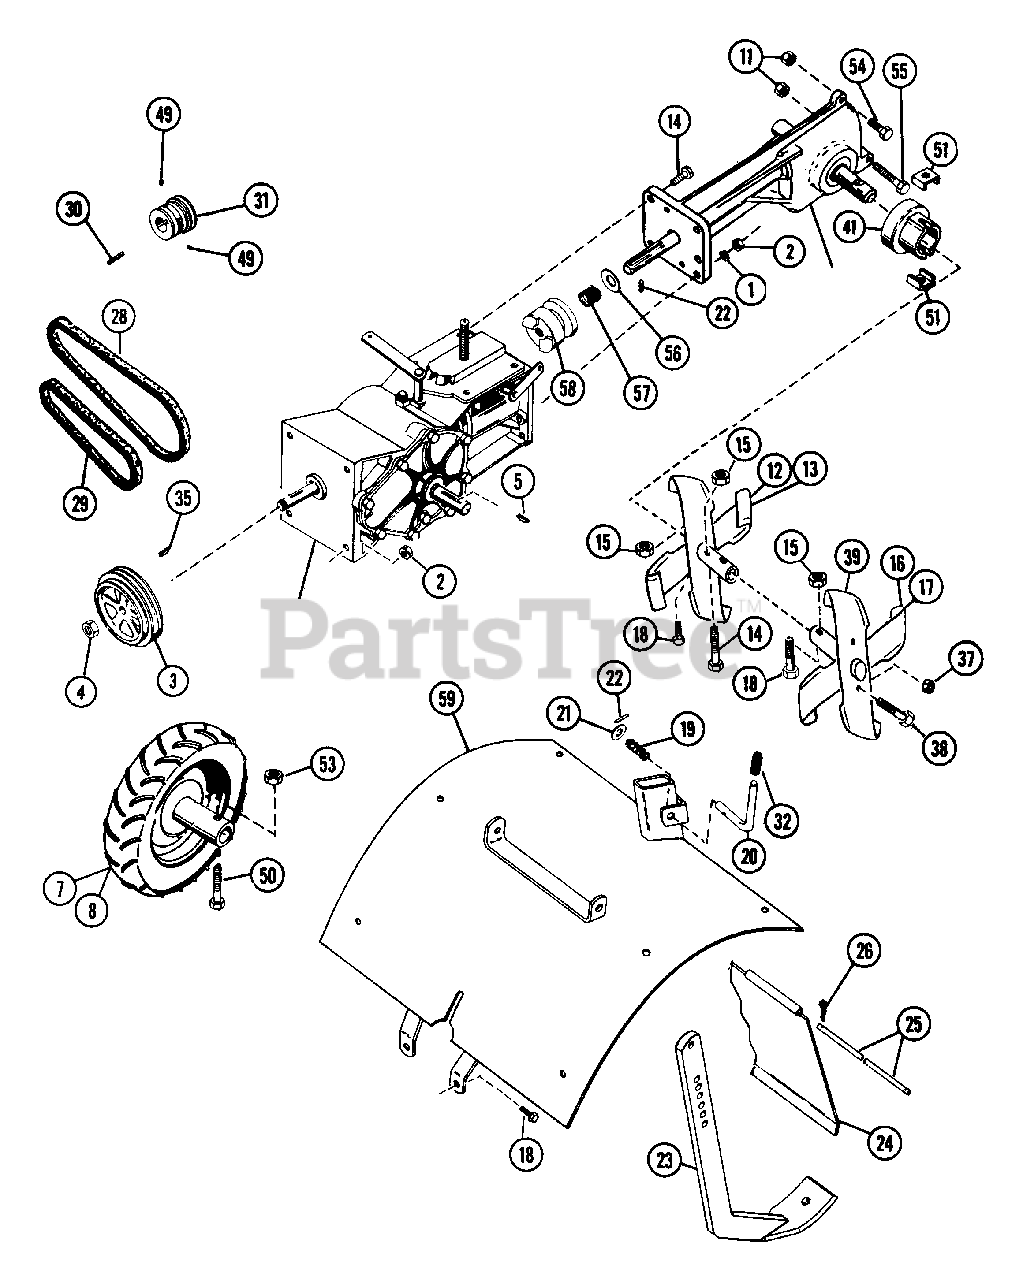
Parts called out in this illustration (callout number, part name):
1	WSHR-LK .375X.115 HVY PL
2	NUT-HEX .375-16
3	DRIVE SHEAVE
4	NUT-LK-CTR .75-16 PL
5	KEY-FTHR .25X1.875X.25 SAE
7	R H TIRE & RIM ASSEMBLY
8	L H TIRE & RIM ASSEMBLY
11	NUT-LK .312-18 GR A PL
12	R H INNER TINE SPOOL
13	L H INNER TINE SPOOL
14	BLT-HEX .38-16X1.75 PL GR2
15	NUT-LK-CTR .375-16 GR A PL
16	R H OUTER TINE SPOOL
17	L H OUTER TINE SPOOL
18	BLT-HEX .38-16X2.00 PL GR2
19	SG-COMP .045X.50X1.187
20	DEPTH REGULATING PIN
21	WSHR-FL-STL .38X.875X.083 PL
22	PIN-ROLL .125X1.00
23	DEPTH SHOE
24	TAILBOARD
25	TAILBOARD PIN
26	PIN COTR .09X.50 PL
28	V-BELT, 4L-WRAPPED
29	V-BELT, 3L-COGGED
30	KEY-WDRF .125X.625X.250 SAE5
31	ENGINE SHEAVE
35	KEY-FTHR .188X1.25X.187 SAE
37	NUT-LK-TOP .437-14 GR C PL
38	BLT-HEX .44-14X1.00 GR5
39	L H TURBO-TINE
39	R H TURBO-TINE
41	DUST CAP
49	SCR-SET .25-20X.25 SKHCUPNY OH
50	BLT-HEX .44-14X2.00 PL GR2
53	NUT-LK .437-14 GR A PL
54	BLT-HEX .31-18X1.25 PL GR2
55	BLT-HEX .31-18X3.50 PL GR2
57	SG-COMP .080X.97X2.18 WLD14
58	TILLER JAW CLUTCH
59	TINE HOOD W/DECALS
